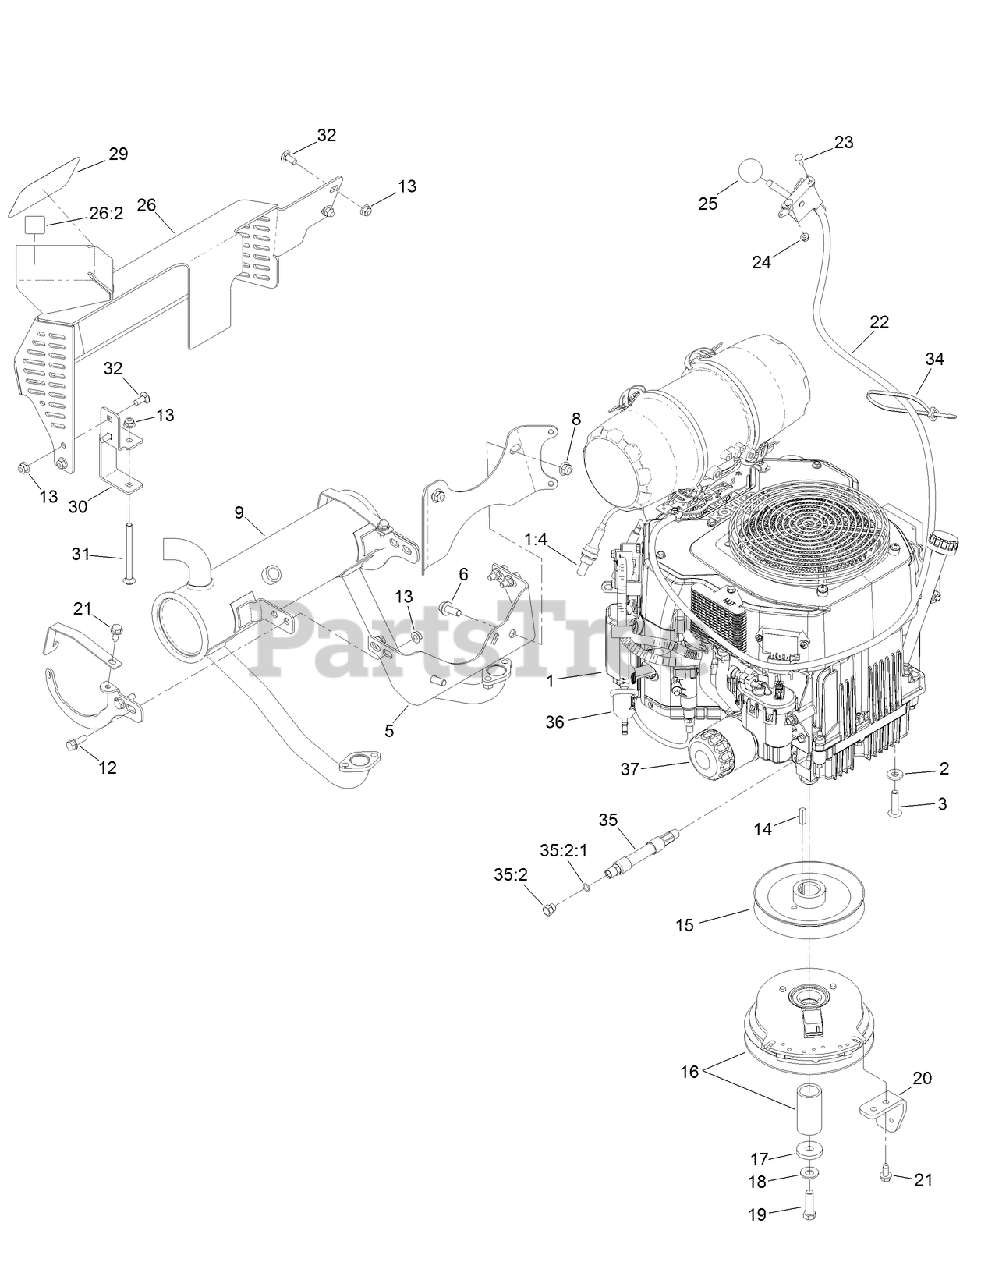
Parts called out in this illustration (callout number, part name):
1	ENGINE-KOHLER, ECV740
1:4	SENSOR-OXYGEN
2	WASHER-BELLEVILLE
3	SCREW-BHTF
5	BRACKET-MUFFLER
6	SCREW-HHF
8	NUT-HF, NI
9	MUFFLER-KOHLER
12	SCREW-HHF
13	NUT-HF
15	PULLEY
16	CLUTCH
17	WASHER
18	WASHER-SPRING
20	STOP-CLUTCH
21	SCREW-HWHTF
22	THROTTLE ASM
23	BOLT-CARR
24	NUT-LOCK, FLANGE
25	KNOB-BALL
26	MUFFLER GUARD ASM
26:2	DECAL-WARNING
29	DECAL
30	BRACKET-MOUNTING, GUARD
31	SCREW-CARR
32	SCREW-CARR
34	TIE-CABLE
35	HOSE ASM
35:2	PLUG-HH
35:2:1	O-RING
36	FILTER-FUEL
37	FILTER-OIL
